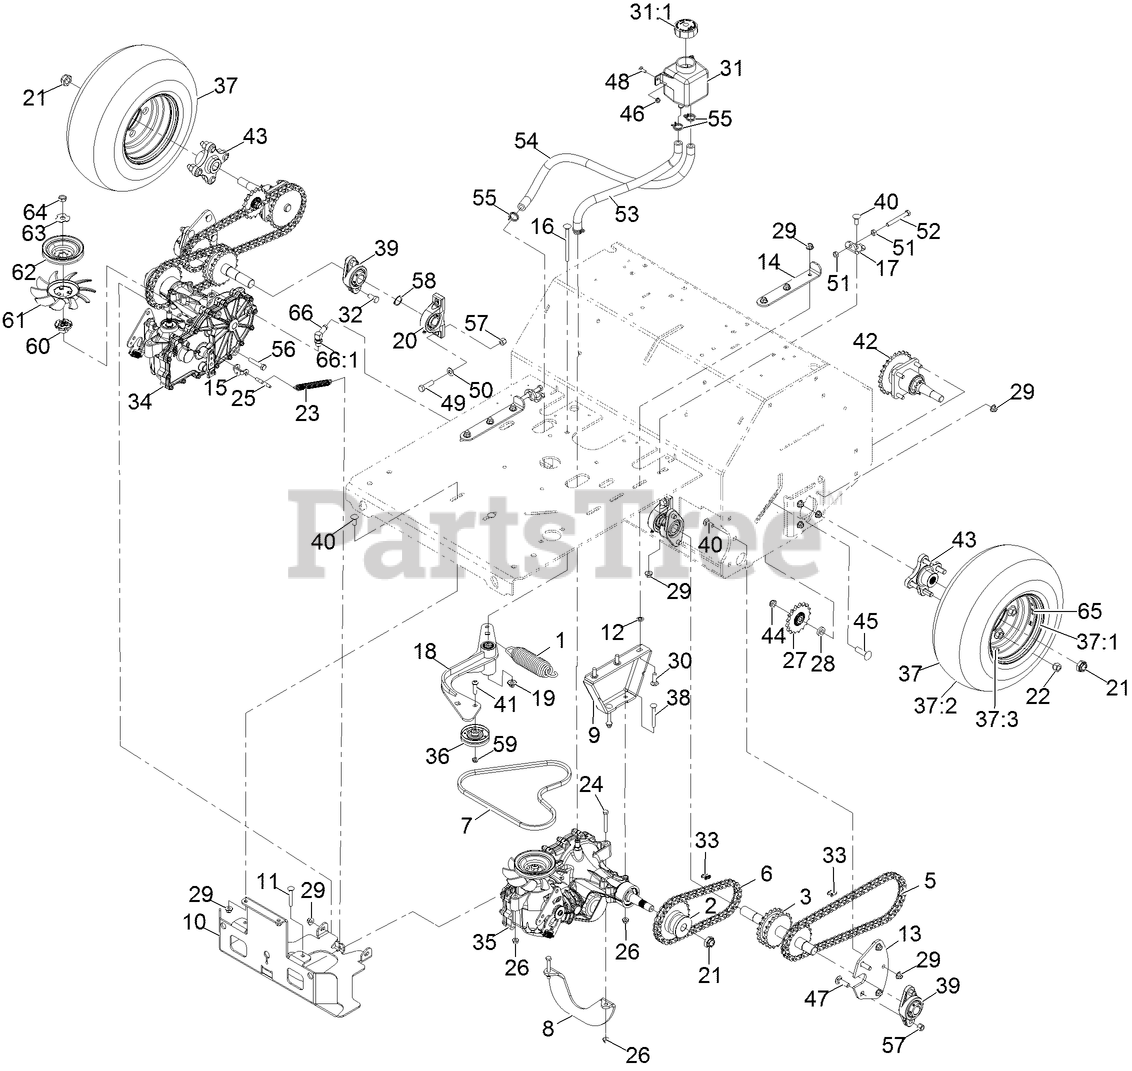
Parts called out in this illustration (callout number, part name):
1	SPRING-EXTENSION
2	HUB-DRIVE, CHAIN
3	JACKSHAFT
5	CHAIN-ROLLER, #50, 65 LINKS
6	CHAIN-ROLLER #50, 47 PITCHES
7	BELT-4L SECTION
8	BRACE-ANGLE
9	MOUNT-TRANSMISSION
10	GUARD-TRANSMISSION
11	BOLT-CARR
12	NUT-PUSH
13	PLATE-JACKSHAFT
14	PLATE-ADJUSTMENT, TRANSMISSION
15	YOKE-BRAKE, PARK
17	BRACKET-HYDRO, ADJUST
18	IDLER ARM ASM
19	NUT-FLANGE, NI
20	BEARING-PILLOW BLOCK
21	NUT-LOCK
22	NUT-LUG
23	SPRING-DOOR
24	SCREW-HH
25	PIN-BRAKE, PARK
26	NUT-HF, NI
27	SPROCKET-IDLER, 17T
28	WASHER
29	NUT-HF, NI
30	BOLT-CARR
31	TANK-HYD
31:1	CAP-RESERVOIR, HYD
32	SCREW-HH
33	LINK-CONNECTING
34	RH TRANSAXLE ASM (NO FAN)
35	LH TRANSAXLE ASM (NO FAN)
36	PULLEY-IDLER
37	TIRE ASM (16 X 6.50-8)
37:1	RIM (8 x 5.375)
37:3	STEM-VALVE
38	SCREW-CARR
39	BEARING-FLANGE, 2 BOLT
40	BOLT-CARR
41	SCREW-HSBH
42	AXLE AND BEARING ASM
43	HUB-OFFSET
44	NUT-LOCK, NI
45	SCREW-CARR
46	NUT-HF
47	BOLT-CARR
48	BOLT-CARR
49	SCREW-HH
50	WASHER-FLAT
51	NUT-HEX
52	SCREW-HH
53	HOSE-HYDRAULIC
54	HOSE-HYDRAULIC
55	CLAMP-HOSE
56	SCREW-HH
57	NUT-LOCK, NI
58	RING-RETAINING
59	NUT-LOCK, NI
60	HUB-PULLEY
62	PULLEY
63	WASHER-SLOTTED
64	NUT-JAM, HEX
65	DECAL-TORQUES, WHEEL HUB AND NUT
66	FITTING-ELBOW, 90
66:1	O-RING
